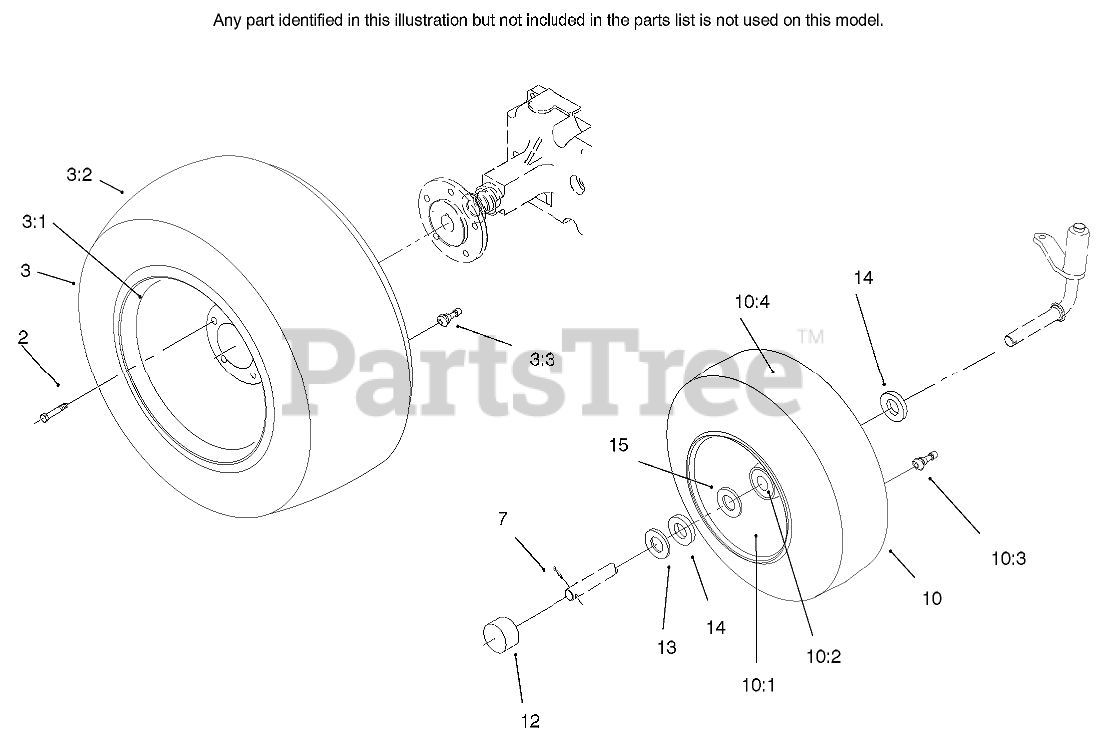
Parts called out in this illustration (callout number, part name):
2	BOLT-LUG
3	Wheel/Tire ASM-Rear
3:1	WHEEL
3:2	TIRE
3:3	VALVE
7	PIN-COTTER
10	FRONT WHEEL ASM
10:1	Wheel ASM
10:2	BEARING-WHEEL
10:3	VALVE
10:4	Tire (16 x 6.5-8) 2-Ply -2 Wheel Axel
10:6	ZERK-GREASE
12	CAP-HUB
13	WASHER-PLAIN
14	WASHER
15	WASHER-SHIM
